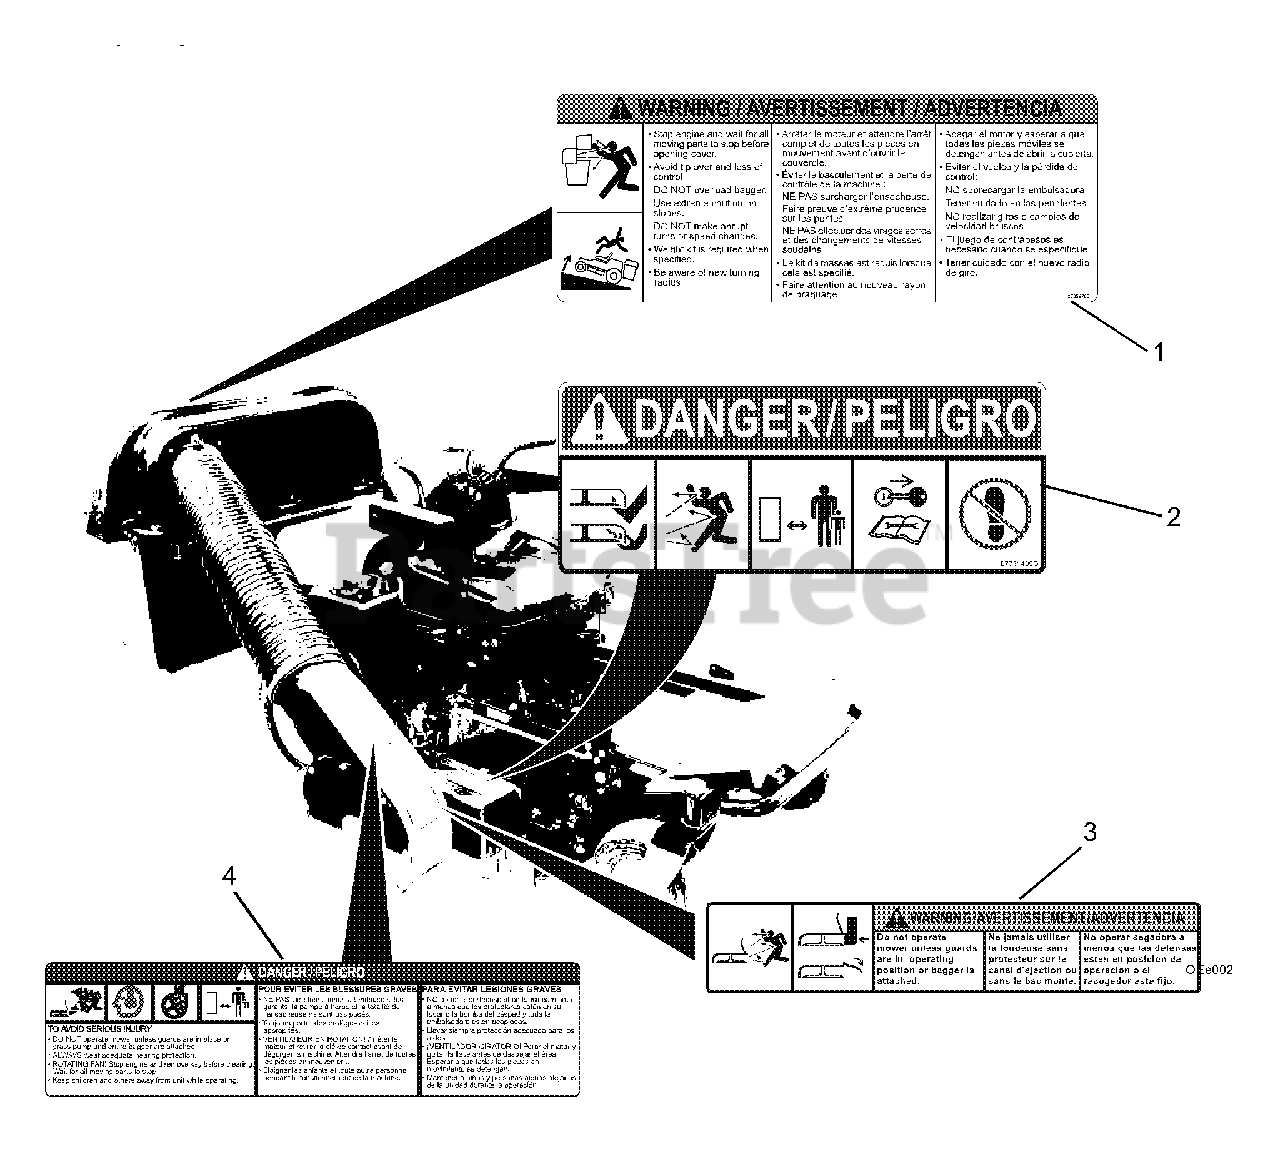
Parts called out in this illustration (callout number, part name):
1	DECAL, BAGGER COVER
2	DECAL, MOWER PAN DANGER
3	DECAL, WARNING
4	DECAL-CAUTION, GRASS PUMP
